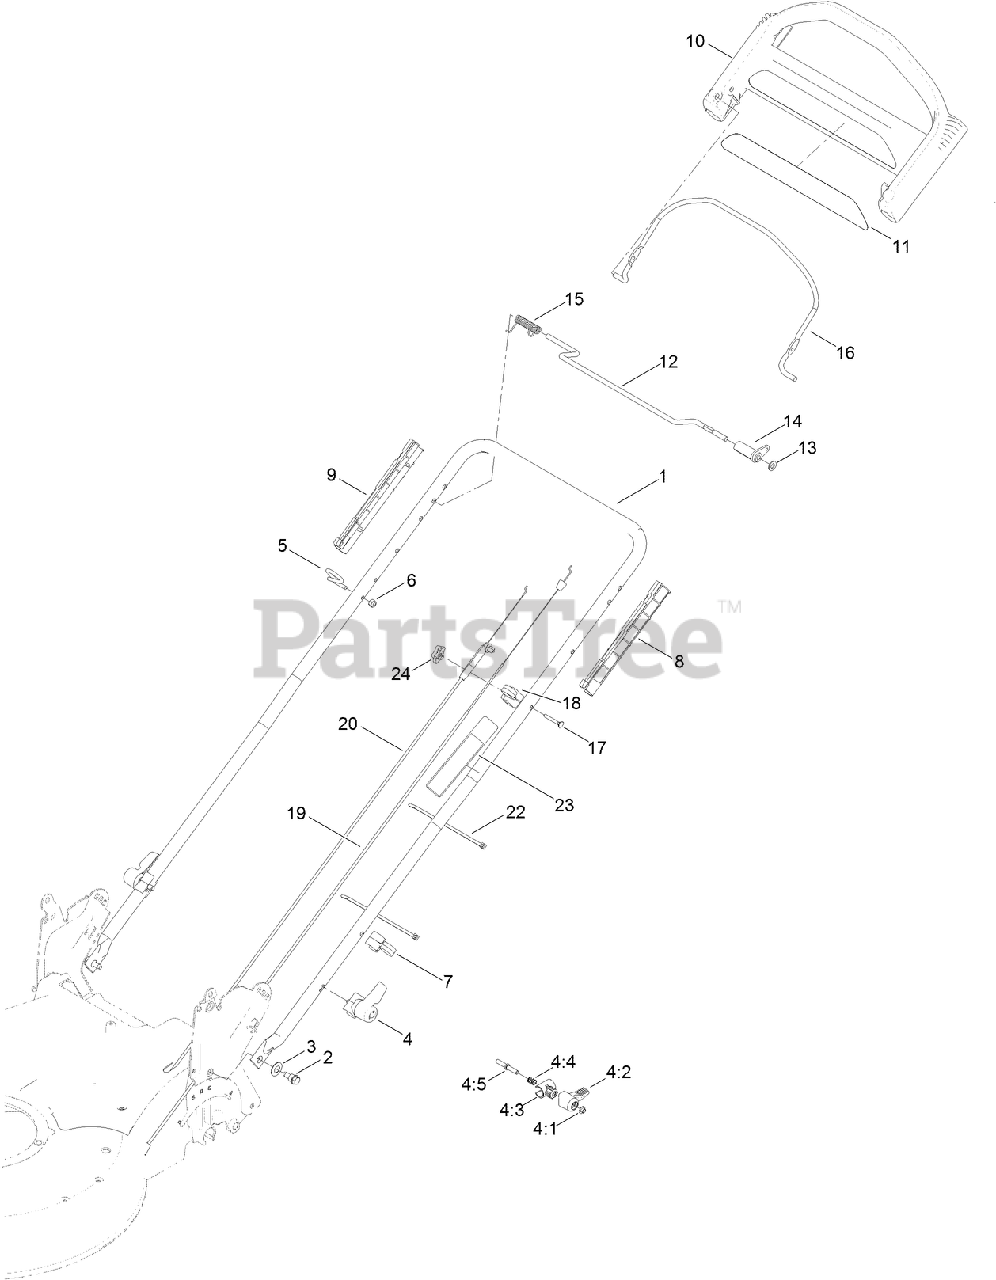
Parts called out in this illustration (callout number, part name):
2	BOLT-SHOULDER
3	WASHER-SPRING, CONICAL
4	QUICK RELEASE ASM
4:1	NUT-PUSH
4:2	LEVER
4:3	ANCHOR-SPRING
4:4	SPRING-COMPRESSION
4:5	ROD-RELEASE
5	GUIDE-ROPE
6	NUT-LOCK, NI
7	GUIDE-CABLE
8	GUIDE-LH
9	GUIDE-RH
10	HANDLE-CONTROL
11	DECAL-HANDLE
12	BAR-CONTROL, TRACTION
13	WASHER-PLAIN
14	LEVER-TRACTION
15	Spring-Torsion
16	Bail-Brake
17	SCREW
18	ANCHOR-CABLE
19	CABLE-TRACTION
20	CABLE-BRAKE
22	TIE-CABLE
23	DECAL-TRACTION, ADJUST
24	KNOB-HANDLE, LOCKING
